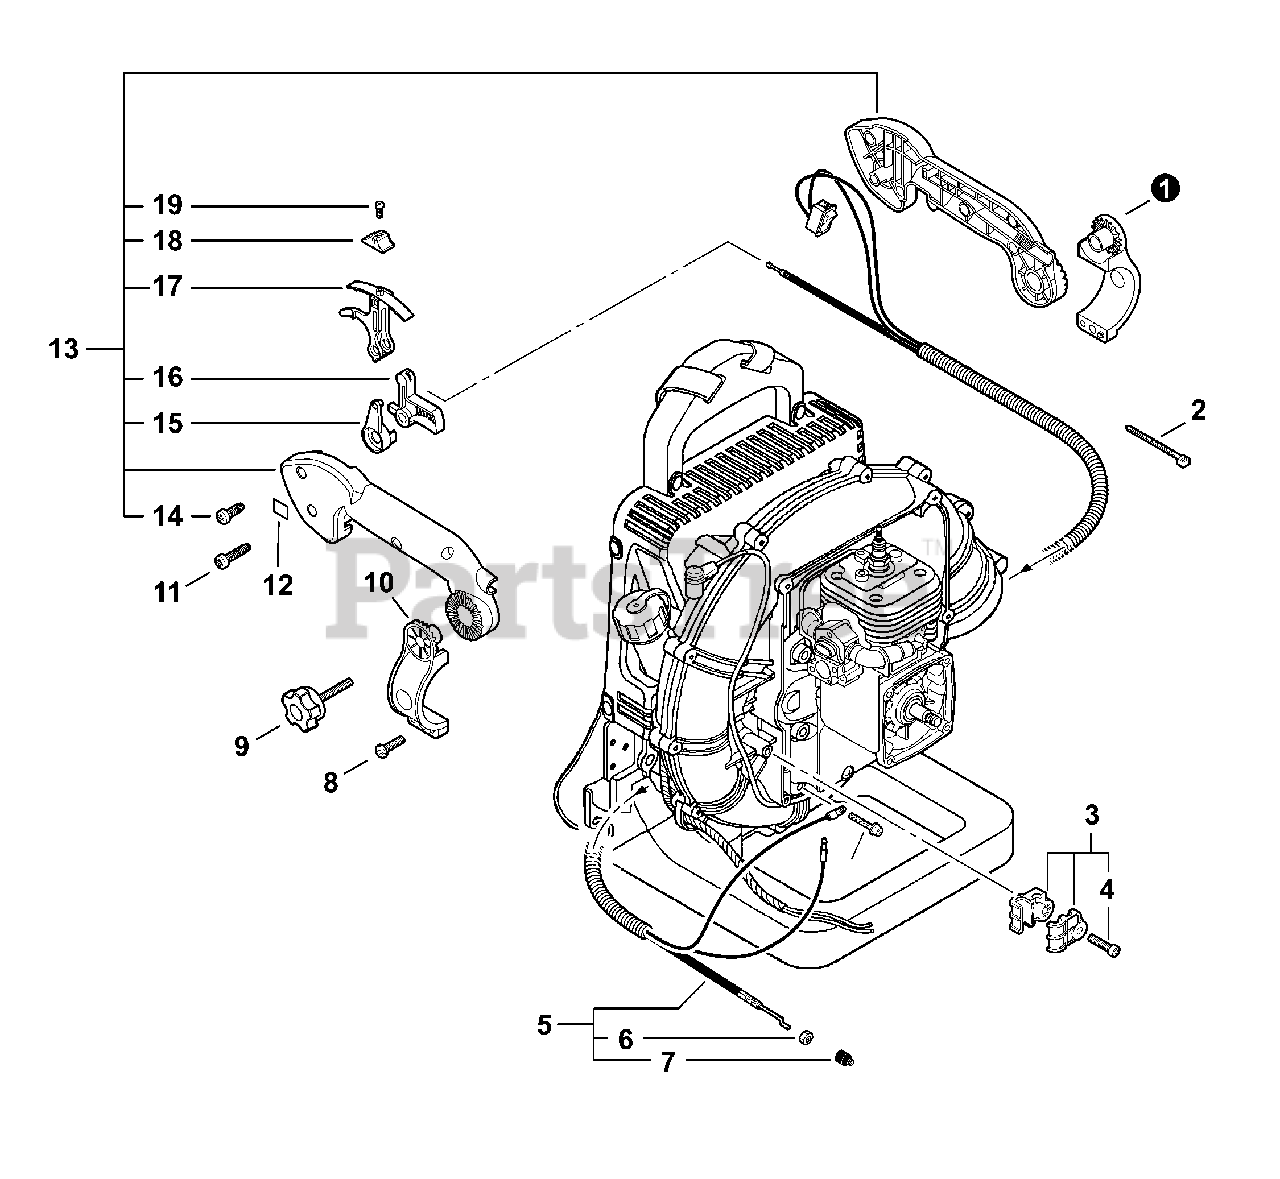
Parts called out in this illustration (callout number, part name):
1	BRACKET, HANDLE - RIGHT
2	STRAP, TIE
3	BRACKET KIT, CABLE
4	BOLT, TAPPING 5×25
5	CONTROL CABLE ASSY
6	NUT, HEX M6
7	CAP, DUST
8	SCREW TAPPING 5×20
9	KNOB, SCREW
10	BRACKET, HANDLE - LEFT
12	LABEL, CAUTION - IDLE
13	CONTROL HANDLE ASSY
15	LEVER, THROTTLE
16	TRIGGER, THROTTLE
17	CONTROL, THROTTLE
18	KNOB, CONTROL
19	SCREW 3×14
